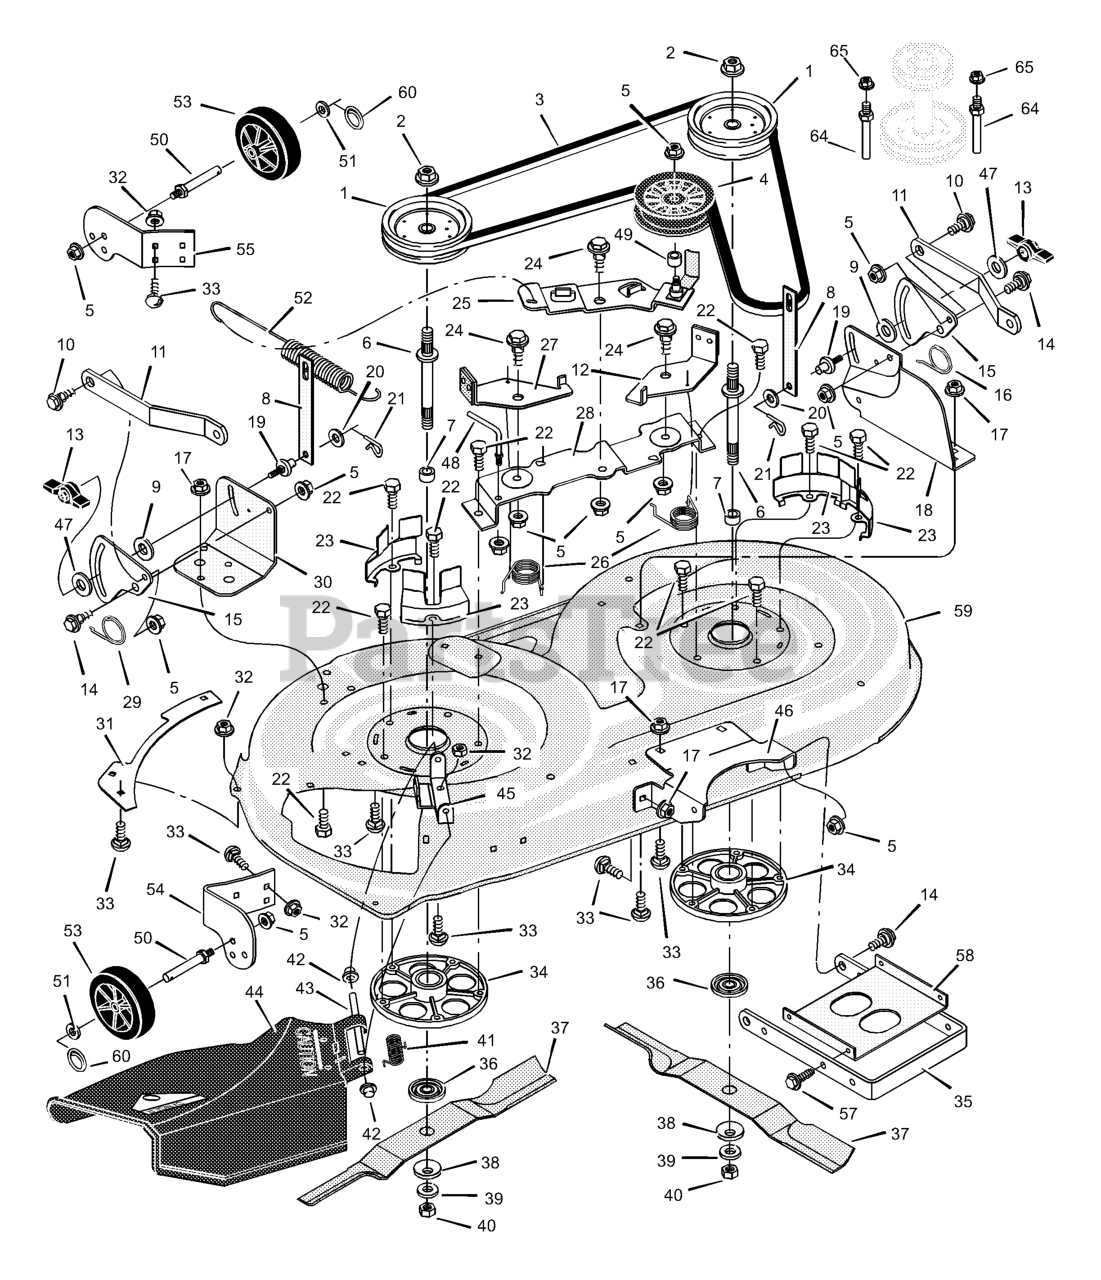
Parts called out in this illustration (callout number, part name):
1	Pulley, Jackshaft
2	Nut, Hex
3	Belt, Mower Drive
4	Pulley, Idler
5	Nut, Flange
6	Jackshaft
8	Link, Lift
9	Pad, Friction
10	Bolt, Shoulder
11	Bracket, Suspension
12	Pad Assembly, Left Brake
13	Knob
14	Bolt, Shoulder
15	Plate, Suspension
17	Nut, Flange
18	Bracket, Suspension
19	Pin, Hanger
21	Pin, Hair
22	Bolt
23	Cover, Pulley
24	Bolt, Shoulder
25	Arm, Idler
27	Pad Assembly, Right Brake
28	Bracket, Brake
30	Bracket, Suspension
32	Nut, Flange
33	Bolt, Carriage
34	Mandrell Housing
35	Bracket, Suspension
36	Adapter, Blade
42	Cap, Push On
43	ROD, Deflector
44	Deflector Assembly
45	Bracket, Deflector Hinge
46	Bracket, Front Hanger
48	Guide, Belt
50	BOLT, Gauge Wheel
52	Spring, Extension
53	Wheel, Gage
54	Bracket, Right Wheel
55	Bracket, Left Wheel
58	Stiffener
59	Housing, Blade, Complete (NO LONGER AVAILABLE)
59	Housing, Blade (Housing Only)
60	Ring, Locking
64	Guide, Belt
65	Nut
